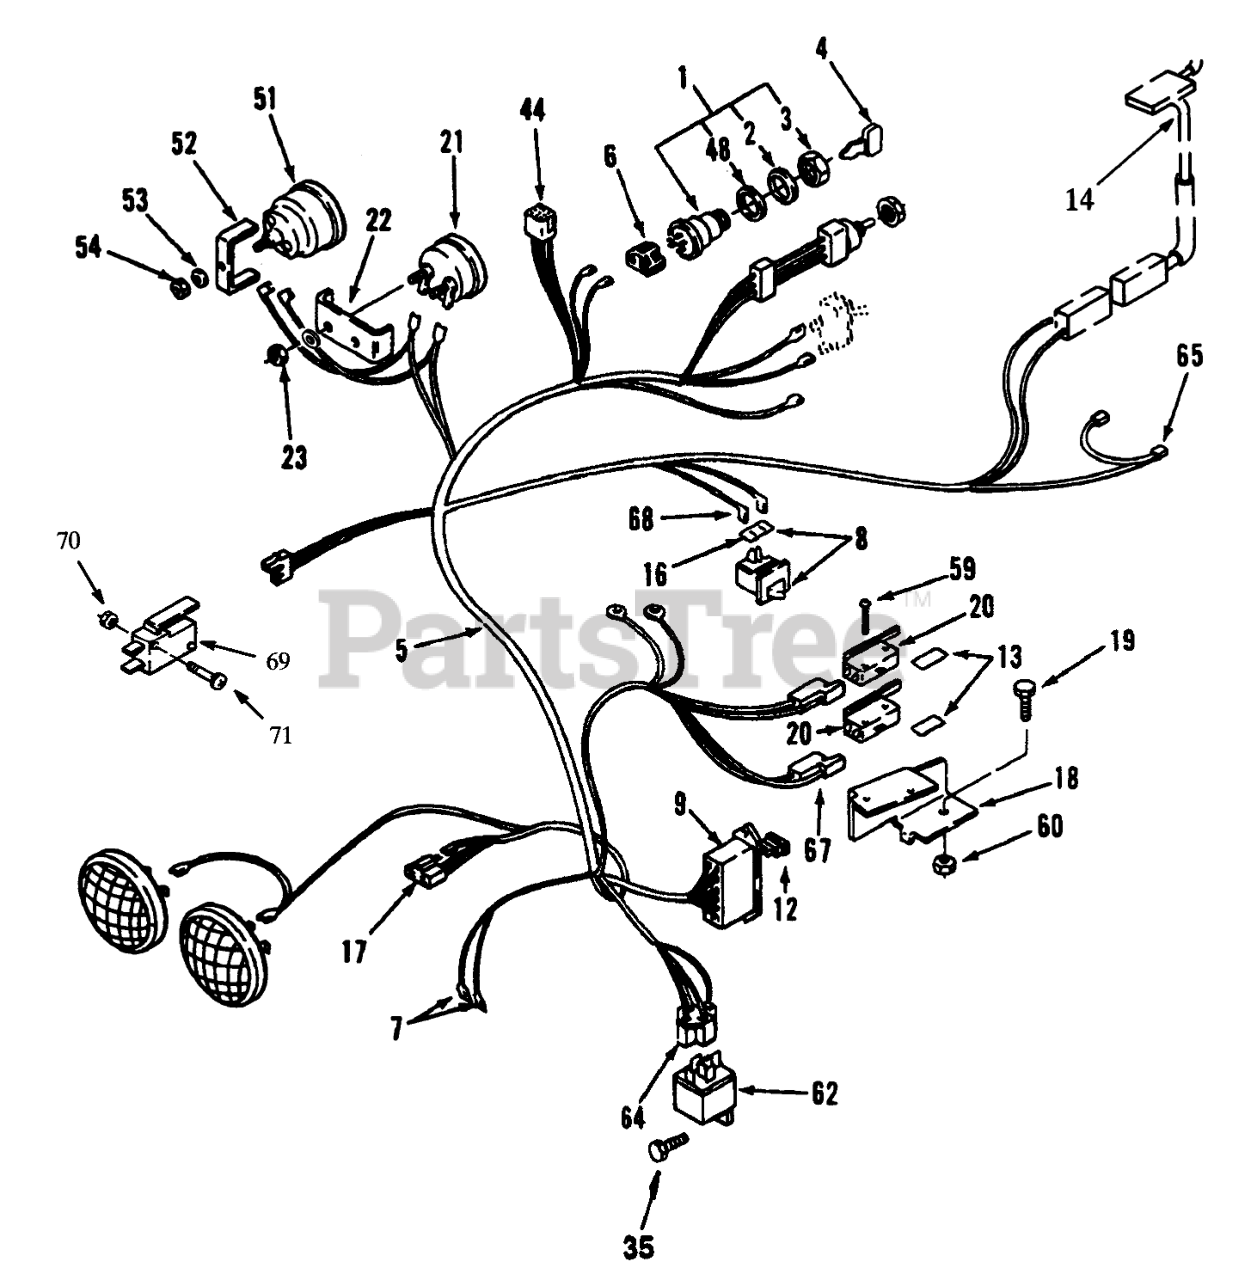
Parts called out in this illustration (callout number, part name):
1	Switch-Ignition (Incl. Ref. #2-3)
2	LOCKWASHER
4	KEY-IGNITION
4	Boot
5	Wiring Harness (Incl. Ref# 6, 7, 9, 17, 44, 65 & 68)
6	CONNECTOR-5 WAY-SERV
7	TERMINAL 10
8	Switch-Clutch Interlock, (Incl. Ref.#16)
9	FUSE-HOLDER 4 WAY
12	FUSE-BLADE, 15 AMP
13	BARRIER - SWITCH
14	SWITCH-SEAT
16	SHIELD-DIRT SPST
17	5-CONTACT CONN BODY
18	BRACKET-SWITCH
19	Bolt
20	SWITCH
21	Voltmeter (Incl. Ref. #23, 24 & 53)
22	CLAMP-MOUNTING
23	NUT-HEX
48	Washer
51	Meter-Hour (Incl. Ref.#52-54)
52	CLAMP-HOUR METER
53	WASHER-LOCK / EXT
54	Hex Nut
59	Screw
60	NUT HEX 4-40 ELAST
62	RELAY
64	TERMINAL 10
65	Sur-Plug
68	Terminal
69	SWITCH
70	NUT HEX 4-40 ELAST
71	Screw
